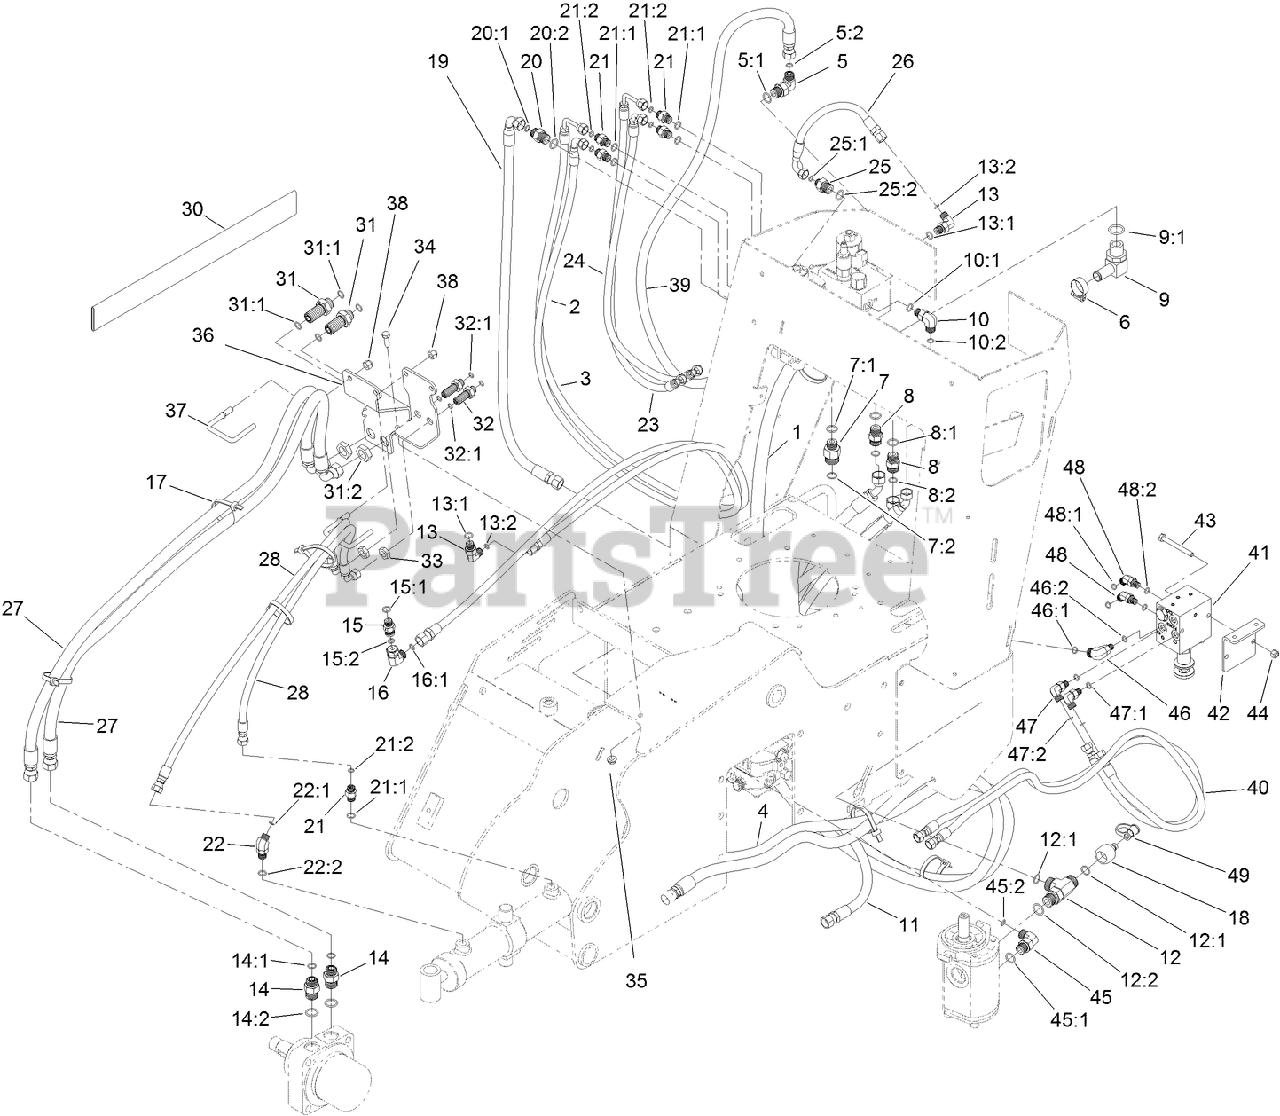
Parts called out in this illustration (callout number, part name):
1	HOSE-HYD
2	HOSE-HYD
3	HOSE-HYD
4	HOSE ASM-HYD
5	FITTING-HYD, 90 DEG
5:1	O-RING
5:2	O-RING
6	CLAMP-HOSE
7	FITTING-STRAIGHT
7:1	O-RING
7:2	O-RING
8	FITTING-STRAIGHT
8:1	O-RING
8:2	O-RING
9	FITTING-ELBOW, 90
9:1	O-RING
10	FITTING-ELBOW, 90 DEG
10:1	O-RING
10:2	O-RING
11	HOSE-HYD
12	FITTING-TEE
12:1	O-RING
12:2	O-RING
13	FITTING-ELBOW, 90 DEG
13:1	O-RING
13:2	O-RING
14	FITTING-STRAIGHT
14:1	O-RING
14:2	O-RING
15	VALVE-CHECK
15:1	O-RING
15:2	O-RING
16	FITTING-HYD, 90 DEG
16:1	O-RING
17	TIE-CABLE
18	NIPPLE
19	HOSE-HYD
20	FITTING-STRAIGHT
20:1	O-RING
20:2	O-RING
21	FITTING-STRAIGHT
21:1	O-RING
21:2	O-RING
22	FITTING
22:1	O-RING
22:2	O-RING
23	HOSE-HYD
24	HOSE-HYD
25	FITTING-STR
25:1	O-RING
25:2	O-RING
26	HOSE-HYD
27	HOSE ASM-HYD
28	HOSE ASM-HYD
30	SLEEVE-PROTECTIVE
31	FITTING-BULKHEAD
31:1	O-RING
31:2	NUT-BULKHEAD
32	UNION-BULKHEAD
32:1	O-RING
33	NUT-LOCK
34	SCREW-HH
35	NUT-HF
36	BRACKET-BULKHEAD
37	GUIDE-HOSE
38	NUT-LOCK, NI
39	HOSE-HYD
40	HOSE-HYD
41	SWEEP MANIFOLD ASM
42	BRACKET-VALVE
43	SCREW-HH
44	NUT-LOCK, NI
45	FITTING-HYD, 90 DEG
45:1	O-RING
45:2	O-RING
46	FITTING-ELBOW, 90 DEG
46:1	O-RING
46:2	O-RING
47	FITTING-ELBOW, 90 DEG
47:1	O-RING
47:2	O-RING
48	FITTING-HYD, 45 DEG
48:1	O-RING
48:2	O-RING
49	CAP-DUST
